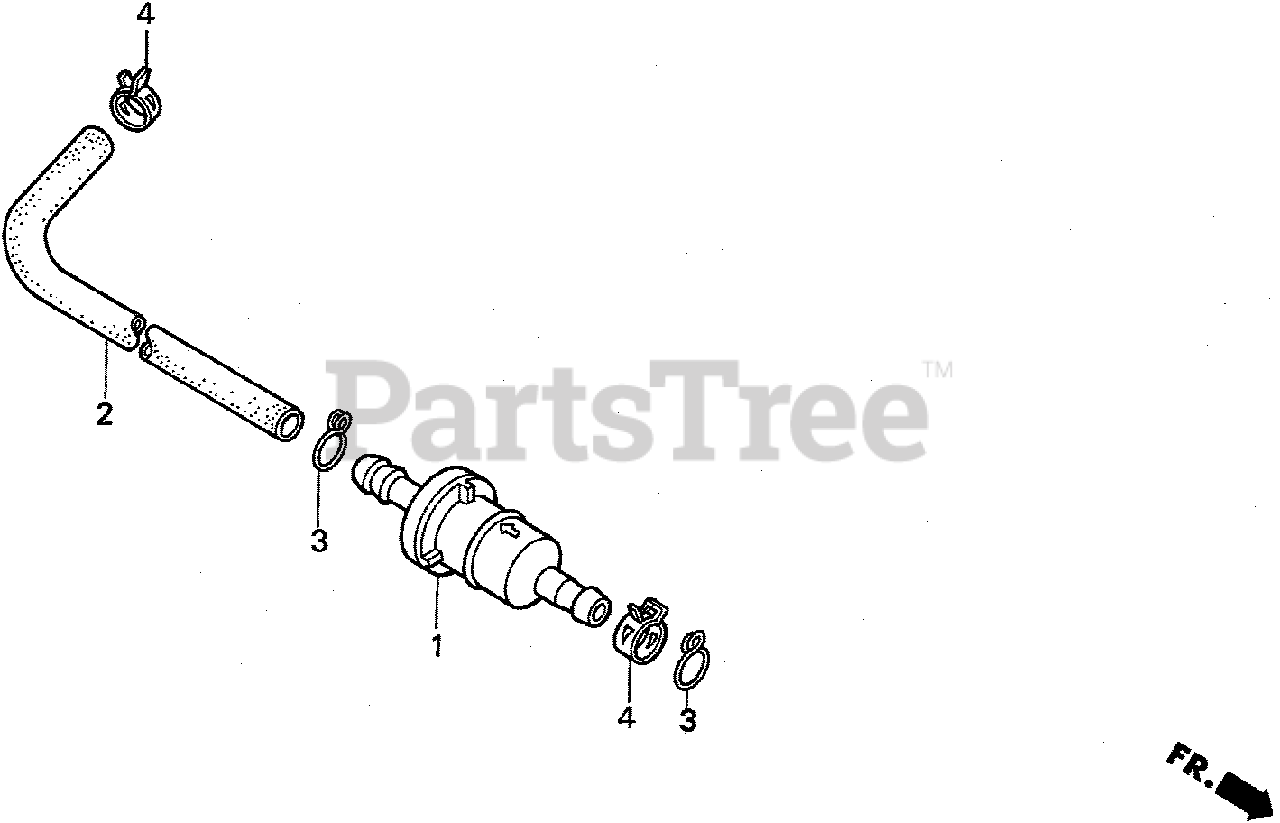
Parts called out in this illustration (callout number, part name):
1	FILTER, FUEL
2	BULK HOSE, FUEL (4.5X3000) (Honda Code 2380558). (4.5X360)
3	CLIP, TUBE (B8)
4	CLIP, TUBE (D8.5)
